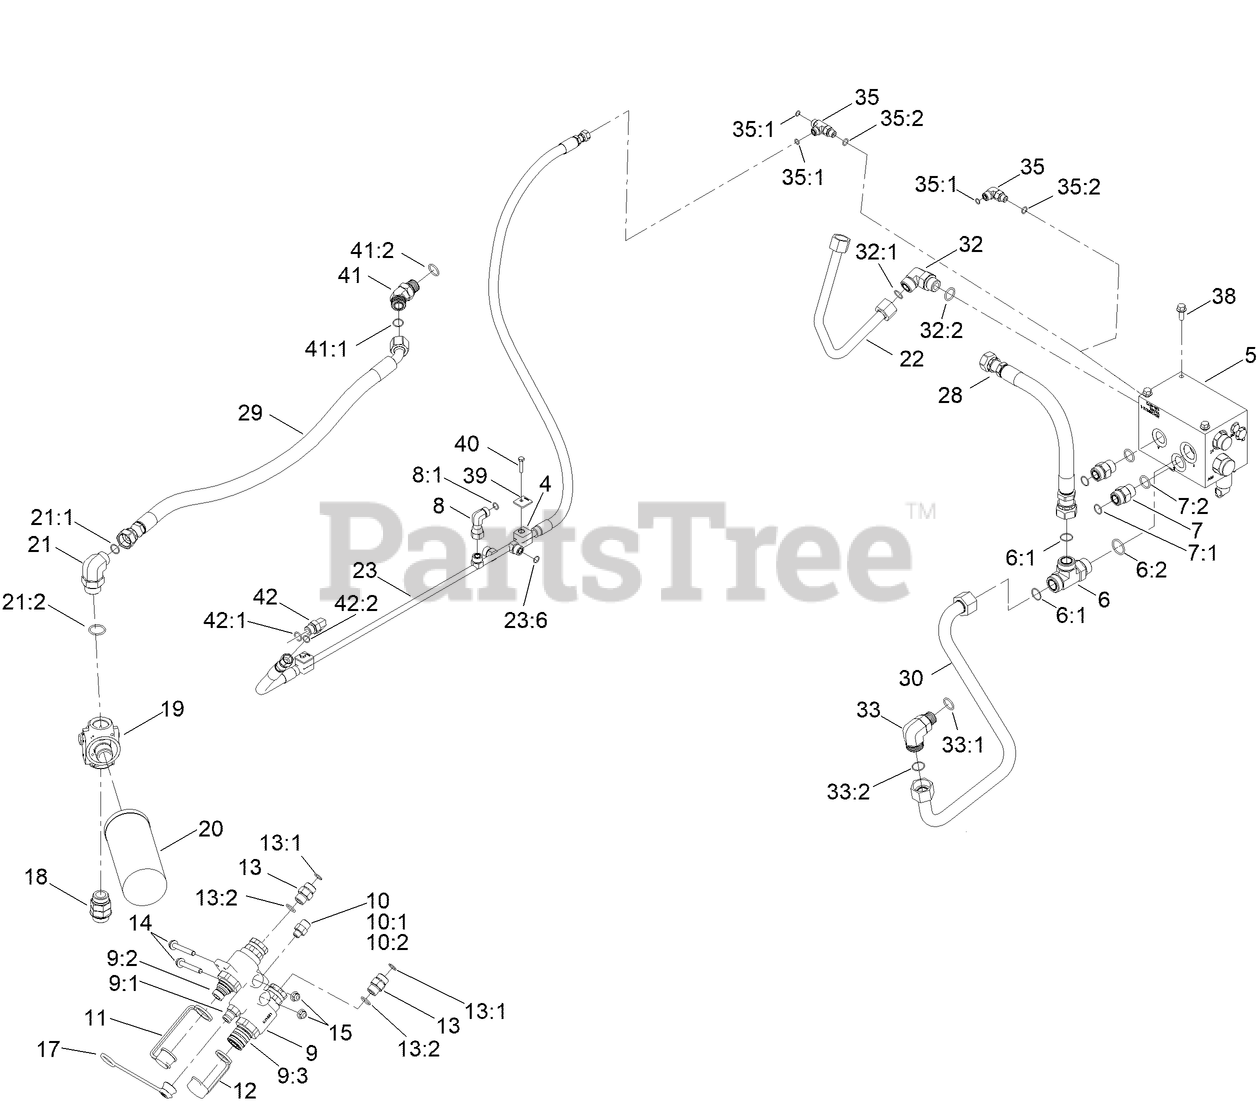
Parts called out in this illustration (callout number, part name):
4	CLAMP-TUBE
5	AUX MANIFOLD ASM
6	FITTING-TEE
6:1	O-RING
6:2	O-RING
7	FITTING-HYD, STRAIGHT
7:1	O-RING
7:2	O-RING
8	FITTING-HYD
8:1	O-RING
9	MANIFOLD-QDC
9:1	KIT-MALE COUPLER, 1/2"
9:2	KIT-MALE COUPLER, 3/8"
9:3	KIT-FEMALE COUPLER, 1/2"
10	FITTING-STRAIGHT
10:1	O-RING
10:2	O-RING
11	CAP-DUST, NIPPLE
12	CAP-DUST, COUPLER
13	FITTING-STRAIGHT
13:1	O-RING
13:2	O-RING
14	SCREW-HFH
15	NUT-HF, NI
17	CAP-DUST, NIPPLE
18	FITTING-STRAIGHT
19	HEAD-FILTER
20	ELEMENT-FILTER
21	FITTING-ELBOW 90
21:1	O-RING
21:2	O-RING
22	HYD TUBE ASM
23	HYD TUBE ASM
23:6	O-RING
28	HYD HOSE ASM
29	HYD HOSE ASM
30	HYDRAULIC TUBE ASM
32	FITTING-ELBOW-90
32:1	O-RING
32:2	O-RING
33	FITTING-ELBOW 90
33:1	O-RING
33:2	O-RING
35	FITTING-ELBOW, 90 DEG
35:1	O-RING
35:2	O-RING
38	SCREW-HHF
39	PLATE-CLAMP,TUBE
40	SCREW-HH
41	FITTING-45 DEG
41:1	O-RING
41:2	O-RING
42	FITTING-ELBOW, 90 DEG
42:1	O-RING
42:2	O-RING
